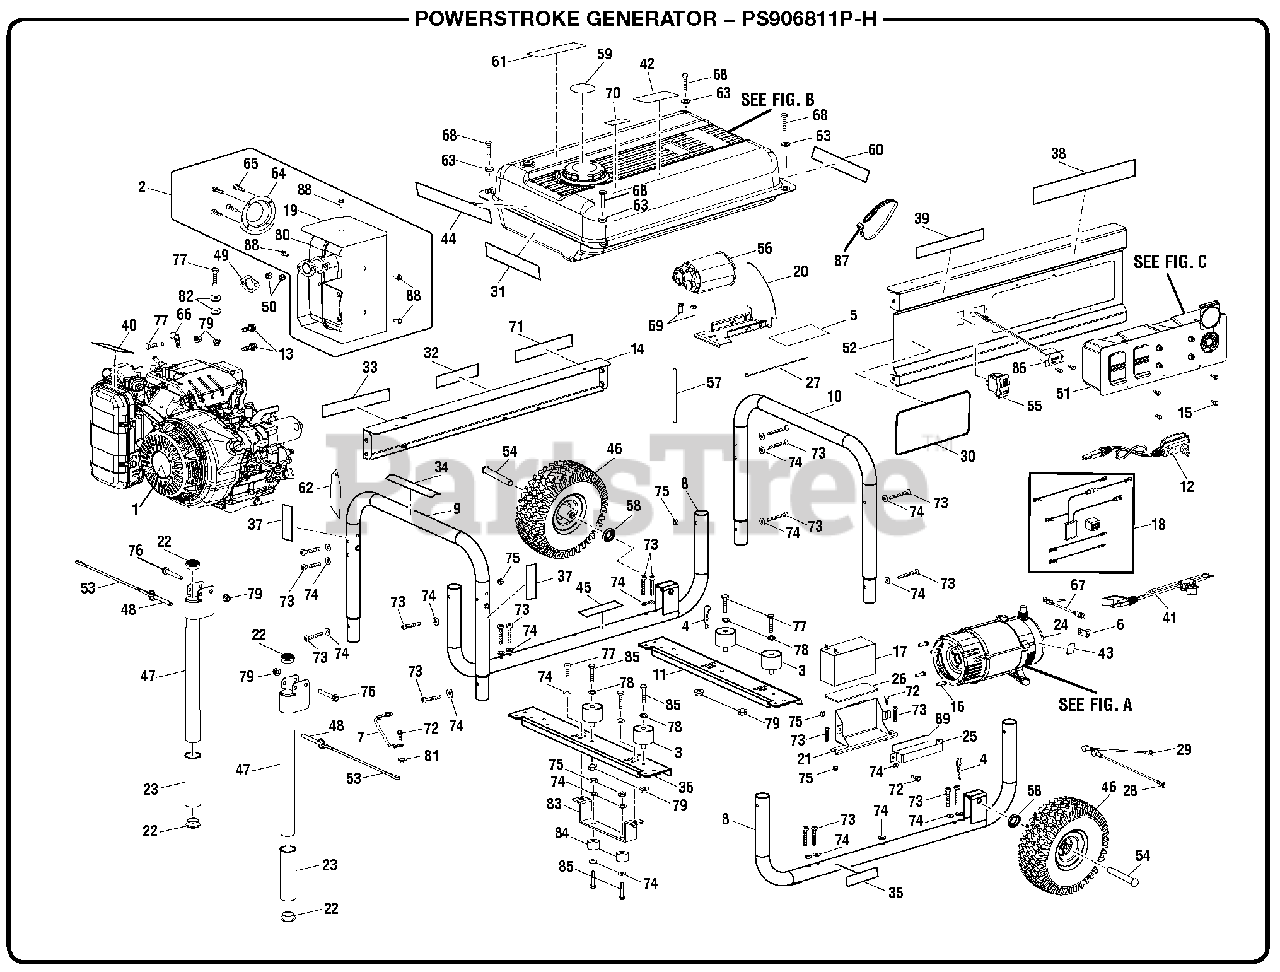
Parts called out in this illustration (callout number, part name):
2	Muffler Assembly
4	Hitch Pin
5	Rubber Sheet
6	Ground Lug
7	Ground Wire Assembly
8	Lower Frame Assembly
9	Tube Assembly (Left)
10	Tube Assembly (Right)
11	Cross Brace
12	Battery Charger
13	Bolt (5/16-24 x 5/8 in.)
14	Back Panel
15	Screw (6-20 x 3/8 in.)
16	Bolt (3/8-16 x 1-1/4 in.)
17	Battery
18	Wire Harness
19	Heat Shield
20	Bracket (Carbon Canister)
21	Battery Box
22	Plastic Cap
23	Handle Grip
24	Generator Head w/AVR
25	Battery Hold Down Bracket
26	Gasket (Battery Hold Down Bracket)
28	Battery Cable (Red)
29	Battery Cable (Black)
30	Logo Label
31	Electric Start Label
32	Hot Surface Label
33	Danger Label
34	Fire Danger Label
35	Engine Lubricant Label
36	Cross Brace
37	Locking Pin Label
38	Honda Label
39	Electric Start Label
40	Choke Label
41	Pigtail (DC)
42	CPSC Label
43	Ground Label
44	Inquires Label
45	Combustion Warning Label
47	Handle Assembly
48	Release Pin (5/16 x 2 in.)
49	Exhaust Gasket
51	Panel Assembly
52	Front Panel
55	Start Switch w/Lock
56	Carbon Canister Assembly
57	Purge Hose
58	Washer (1/2 in.)
59	Fuel Stabilizer Label
60	Ground Warning Label
61	Fuel Warning Label
63	Washer (1/4 in.)
64	Spark Arrestor
65	Screw (8-32 x 3/8 in., Pan Hd.)
66	J-Clamp (1/2 in.)
67	Bonding Wire
68	Screw (1/4-14 x 1-1/4 in.)
69	Screw (#10-16 x 3/4 in.)
70	E85 Label
71	Fire Distance Label
72	Screw (M6 x 16 mm, Hex Hd.)
73	Screw (M6 x 50 mm, T30 Torx Pan Hd.)
74	Washer (M6)
75	Lock Nut (M6)
76	Bolt (M8 x 55 mm, Hex Hd.)
77	Bolt (M8 x 35 mm, Hex Hd.)
78	Washer (M8)
79	Flange Lock Nut (M8 x 1.25)
81	Star Washer (M6)
82	Washer (5/16 in)
83	Foot Bracket
85	Bolt (M6 x 25 mm, Hex Hd.)
86	Hour Meter
87	Cable Tie 18.6 in.)
88	Bolt (M6 x 9 mm)
89	Battery Bracket Gasket
90	Bolt (M6 x 25 mm, Hex Hd.)
